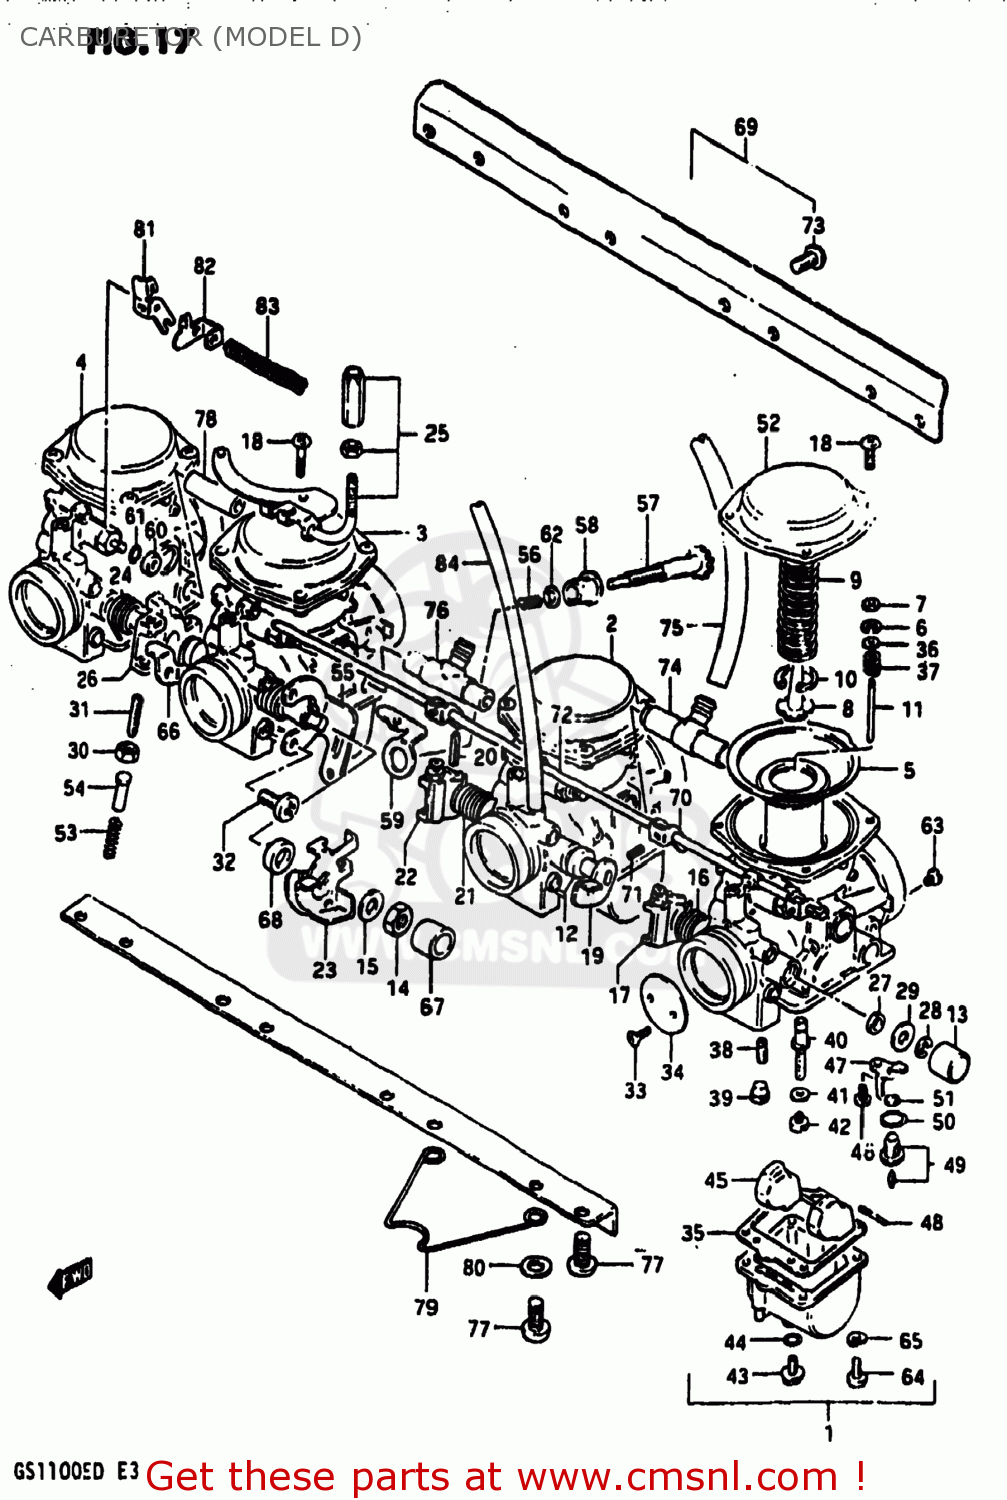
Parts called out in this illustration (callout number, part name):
1	CARBURETOR ASSEMBLY
2	CARBURETOR ASSEMBLY
3	CARBURETOR ASSEMBLY
4	CARBURETOR ASSEMBLY
5	DIAPHRAGM ASSEMBLY
6	CLIP,NEEDLE
7	RING
8	HOLDER,GUIDE
9	SPRING
10	E RING
11	NEEDLE,JET
12	GASKET
13	CAP,THROTTLE SHAFT
14	NUT 8MM
15	WASHER
16	SPRING,THROTTLE SHAFT
17	SHAFT,THROTTLE
18	SCREW
19	SHAFT,THROTTLE
20	PIN,THROTTLE SHAFT
21	SPRING,THROTTLE SHAFT
22	LEVER,THROTTLE SHAFT
23	LEVER ASSEMBLY,THROTTLE
24	SPRING,THROTTLE SHAFT
25	BRACKET
26	SHAFT,THROTTLE
27	SEAL
28	E RING
29	GASKET,THROTTLE SHAFT (NAS)
30	NUT
31	SCREW
32	SCREW
33	SCREW
34	VALVE,THROTTLE
35	GASKET,FLOAT CHAMBER (NAS)
36	WASHER
37	SPRING
38	JET,PILOT(45)
39	PLUG,NEEDLE JET
40	JET,NEEDLE
41	WASHER,NEEDLE NOZZLE
42	JET,MAIN(112.5)
43	PLUG,DRAIN
44	GASKET (NAS)
45	FLOAT
46	SCREW 4X6
47	PLATE,NEEDLE VALVE FITING
48	PIN,FLOAT
49	VALVE ASSEMBLY,NEEDLE
50	O-RING,NEEDLE VALVE
51	FILTER
52	COVER,DIAPHRAGM
53	SPRING,THROTTLE SCREW
54	PIN,THROTTLE LEVER
55	BRACKET,THROTTLE ADJUST
56	SPRING
57	SCREW
58	BUSH
59	BRACKET,THROTTLE ADJUST
60	CAP,STARTER VALVE
61	O RING
62	WASHER
63	JET
64	SCREW
65	WASHER,LOCK
66	SHAFT,THROTTLE
67	RING
68	RING
69	CARBURETOR ASSEMBLY
70	LEVER
71	SCREW
72	SHAFT,STARTER
73	SCREW M5X12 DIN 7985/N
74	NIPPLE
75	HOSE,CARBURETOR
76	NIPPLE
77	SCREW
78	NIPPLE
79	CLIP
80	WASHER
81	LEVER
82	LEVER
83	SPRING
84	HOSE
